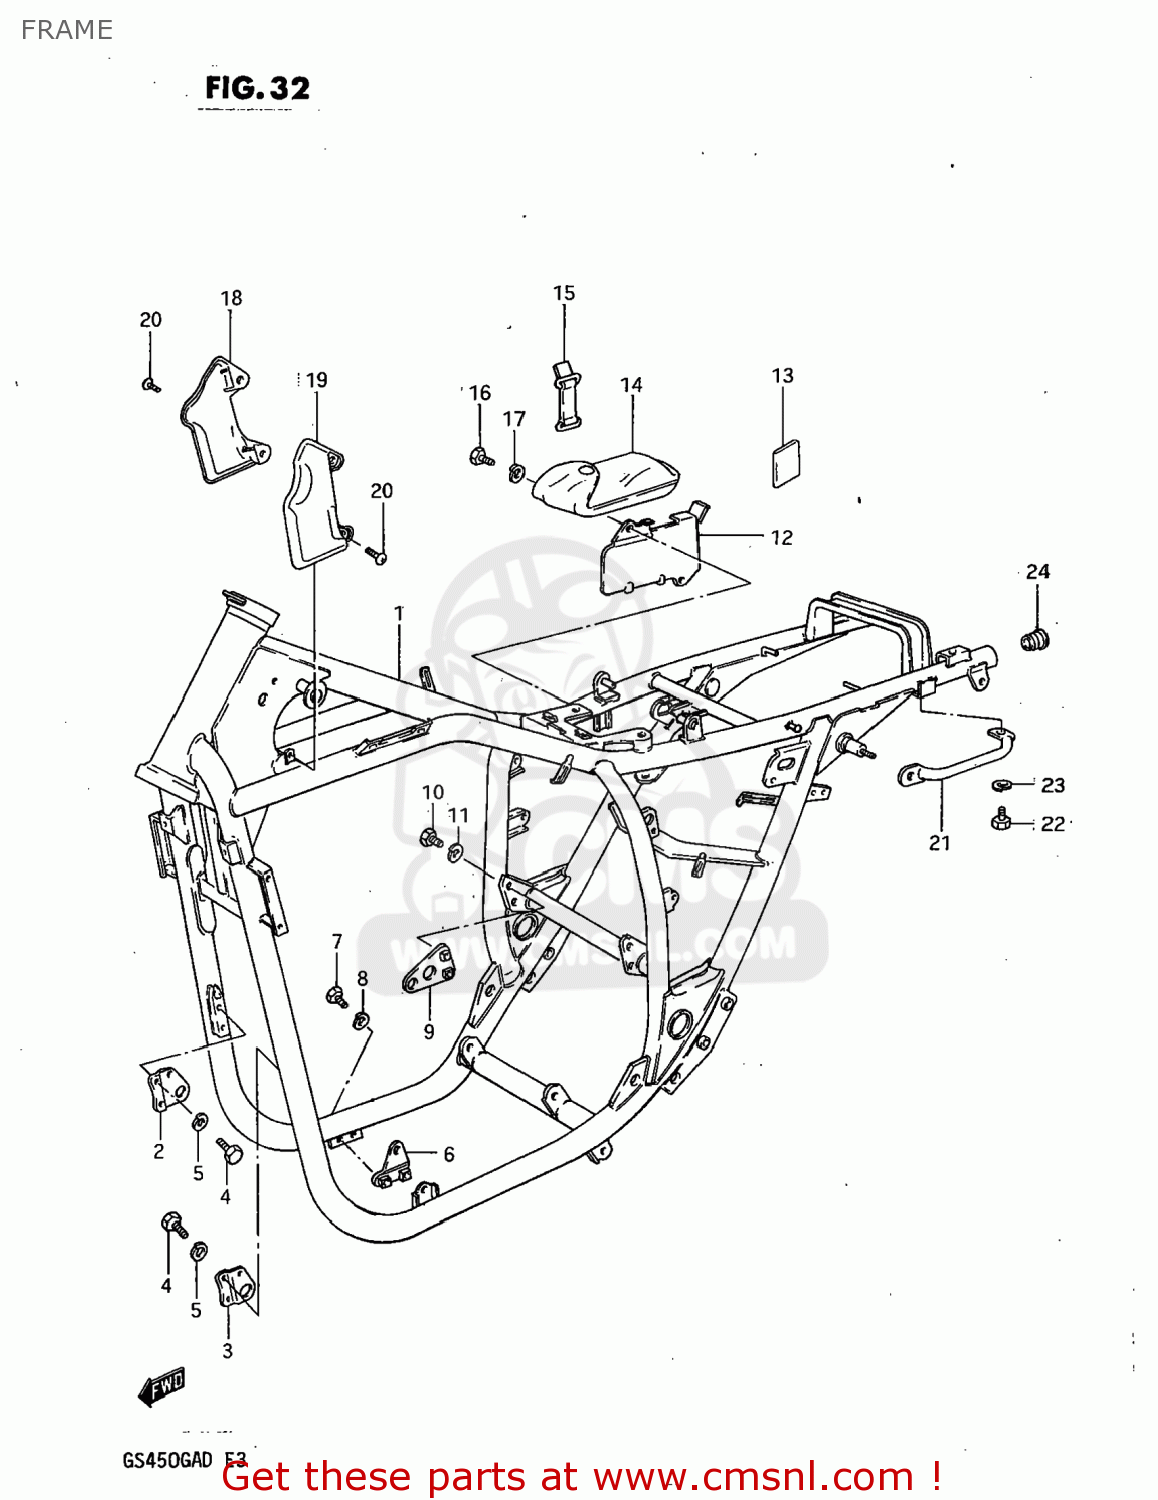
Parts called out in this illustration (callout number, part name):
1	FRAME
2	PLATE,ENGINE MOUNTING
3	PLATE,ENGINE MOUNTING
4	BOLT
5	LOCK WASHER
6	PLATE,MOUNTING NO.2,LEFT
7	BOLT
8	LOCK WASHER
9	PLATE,ENGINE MOUNTING
10	BOLT
11	LOCK WASHER
12	HOLDER,TOOL
13	PROTECTOR(170X95X3.0)
14	TOOL SET
15	BAND
16	BOLT
17	LOCK WASHER
18	COVER,FRAME HEAD,RIGHT
19	COVER,FRAME HEAD,LEFT
20	SCREW
21	GRIP,FRAME
22	BOLT
23	WASHER
24	CAP(OD:26)
